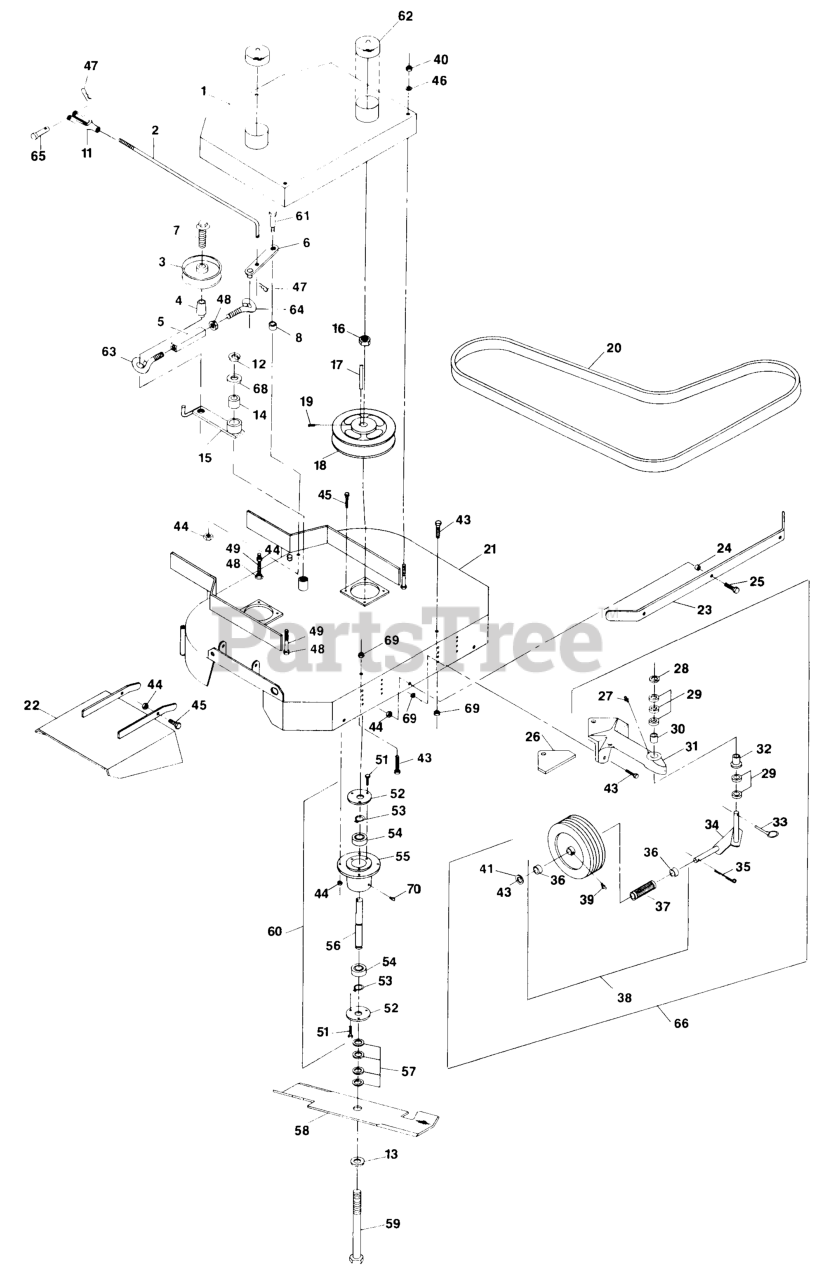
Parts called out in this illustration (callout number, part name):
5	BODY-TURNBUCKLE
11	YOKE-ADJUSTABLE
14	BEARING,POWDERED METAL
18	PULLEY,CAST IRON
19	SCREW-SET
20	BELT,MAIN DRIVE BLADES
30	SLEEVE,BEARING
47	PIN-COTTER
49	BOLT,TAP HH
51	SCRWMACH PHS
55	HOUSING,CUTTER
56	SPINDLE,CUTTER
60	HOUSING,CUTTER COMPLETE
61	BOLT,SHLDR KSKH
62	CAP,SPINDLE GUARD
63	EYEBOLT-THREAD, LH
64	EYEBOLT-THREAD, RH
65	PIN-CLEVIS
68	WASHER-SPINDLE
